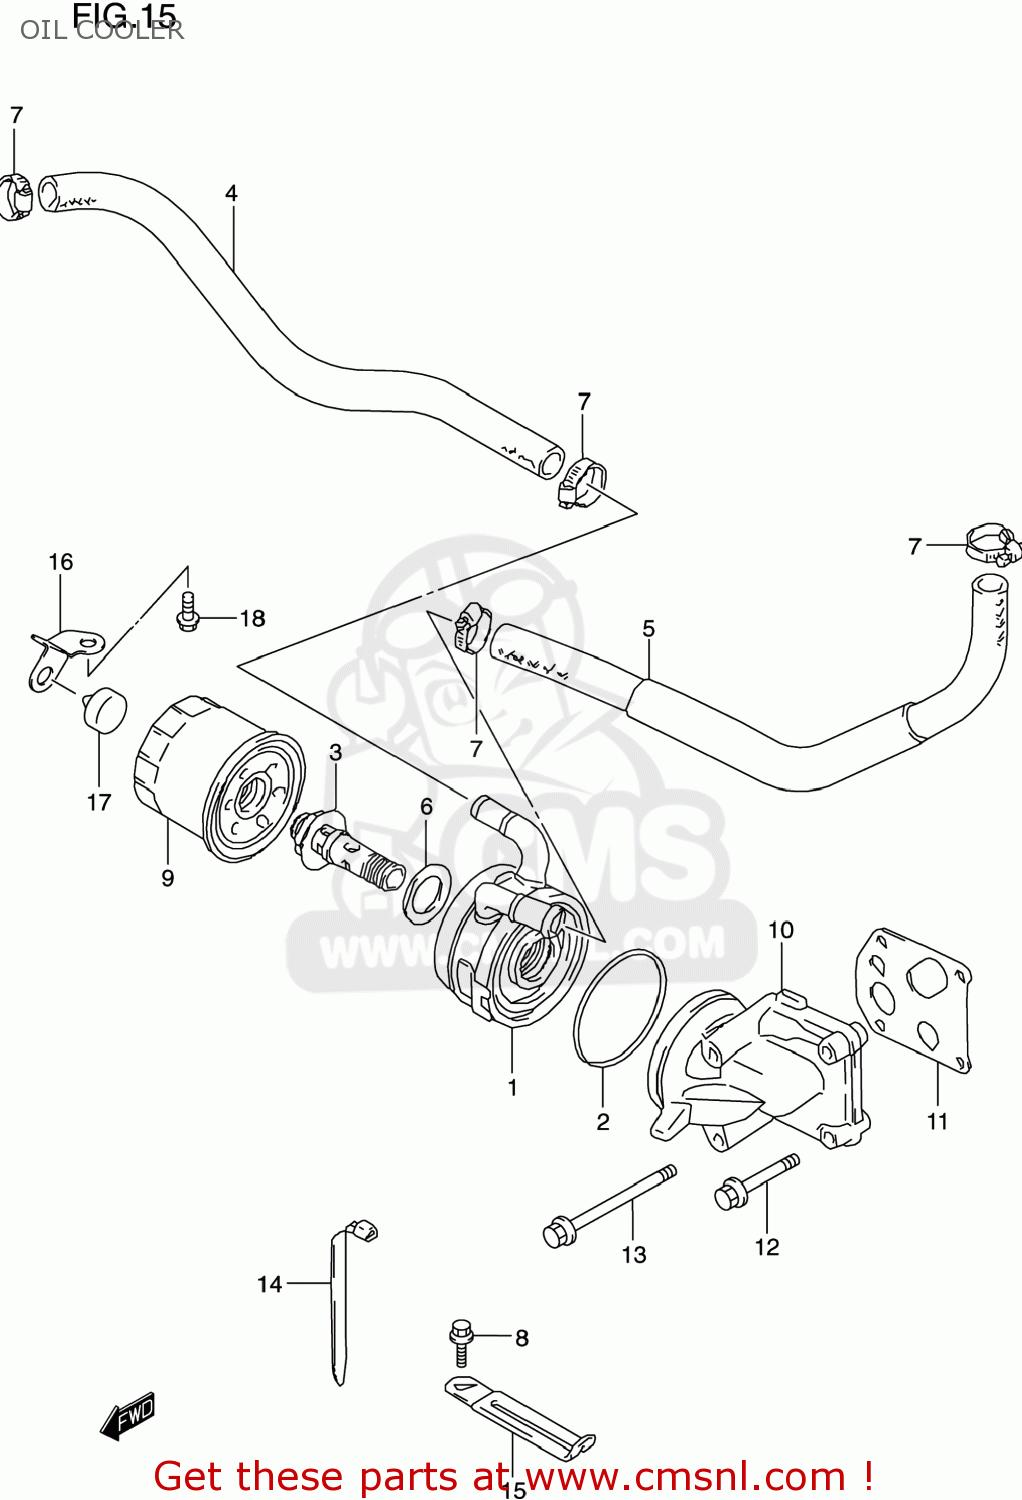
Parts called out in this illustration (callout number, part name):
1	COOLER ASSY,OIL
2	O RING(D:3.1,ID:63.9)
3	BOLT,OIL COOLER UNION
4	HOSE,OIL COOLER WATER OUT
5	HOSE,OIL COOLER WATER IN
6	SHIM
7	CLAMP
8	BOLT 6X12
9	FILTER ASSEMBLY,ENGINE OIL
10	HOLDER,OIL FILTER
11	GASKET,OIL FILTER HOLDER
12	BOLT(6X40)
13	BOLT(6X65)
14	CLAMP(L:235)
15	CLAMP(L:80 T:1.0)
16	PLATE,OIL COOLER DAMPER
17	CUSHION(11.5X22X20)
18	BOLT
